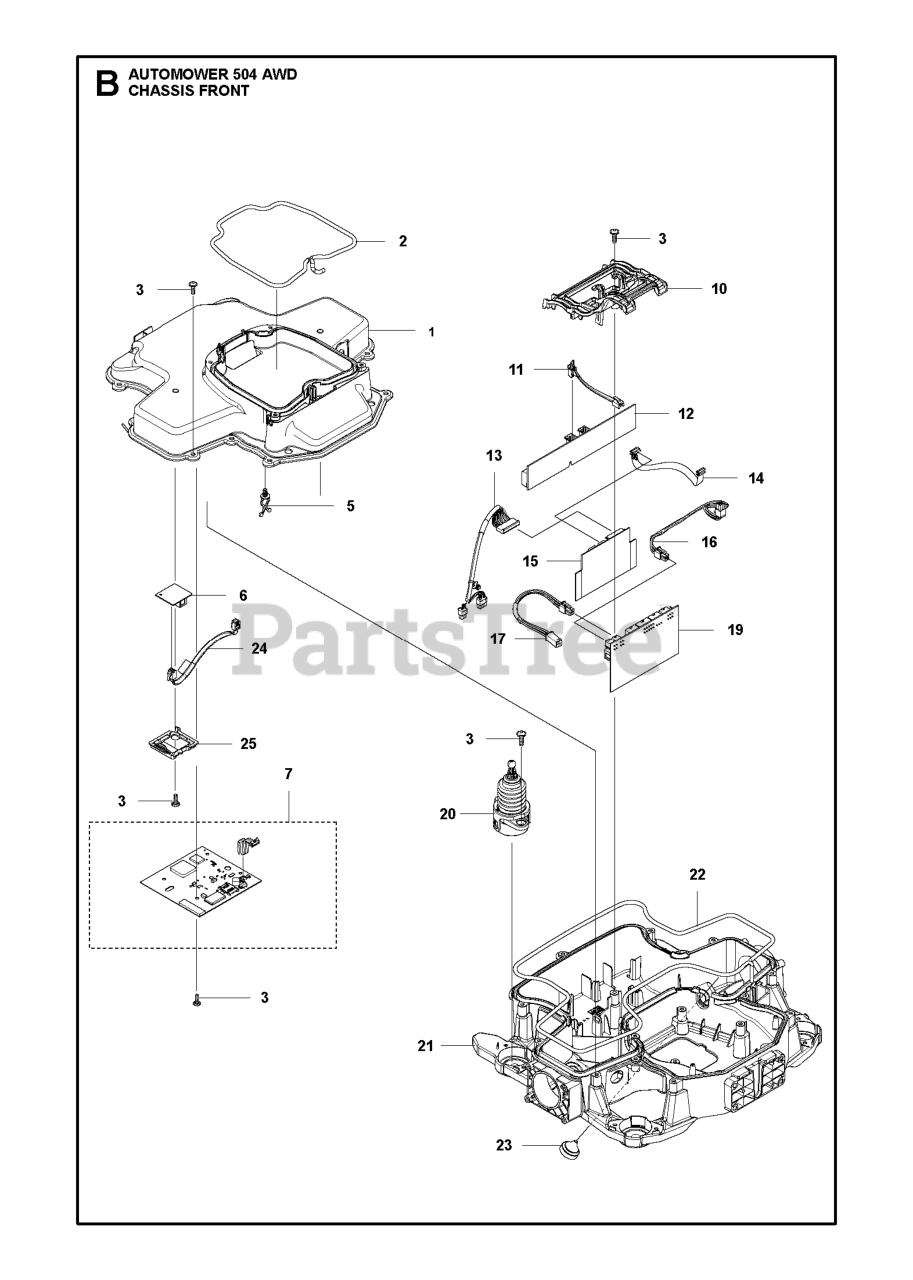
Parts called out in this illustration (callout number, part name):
1	Chassis
2	Seals
3	SCREW 14MM
5	HOLDER TWIST LOCK
6	Circuits
10	Holders
11	Wires
12	Circuits
13	Wires
14	Wires
15	PRINTED CIRCUIT ASSY ULTRASONI
16	Wires
17	Wires
19	Circuits
20	Joystick
21	Chassis
22	Seals
23	GROMMET M16
24	Wires
25	Holders
